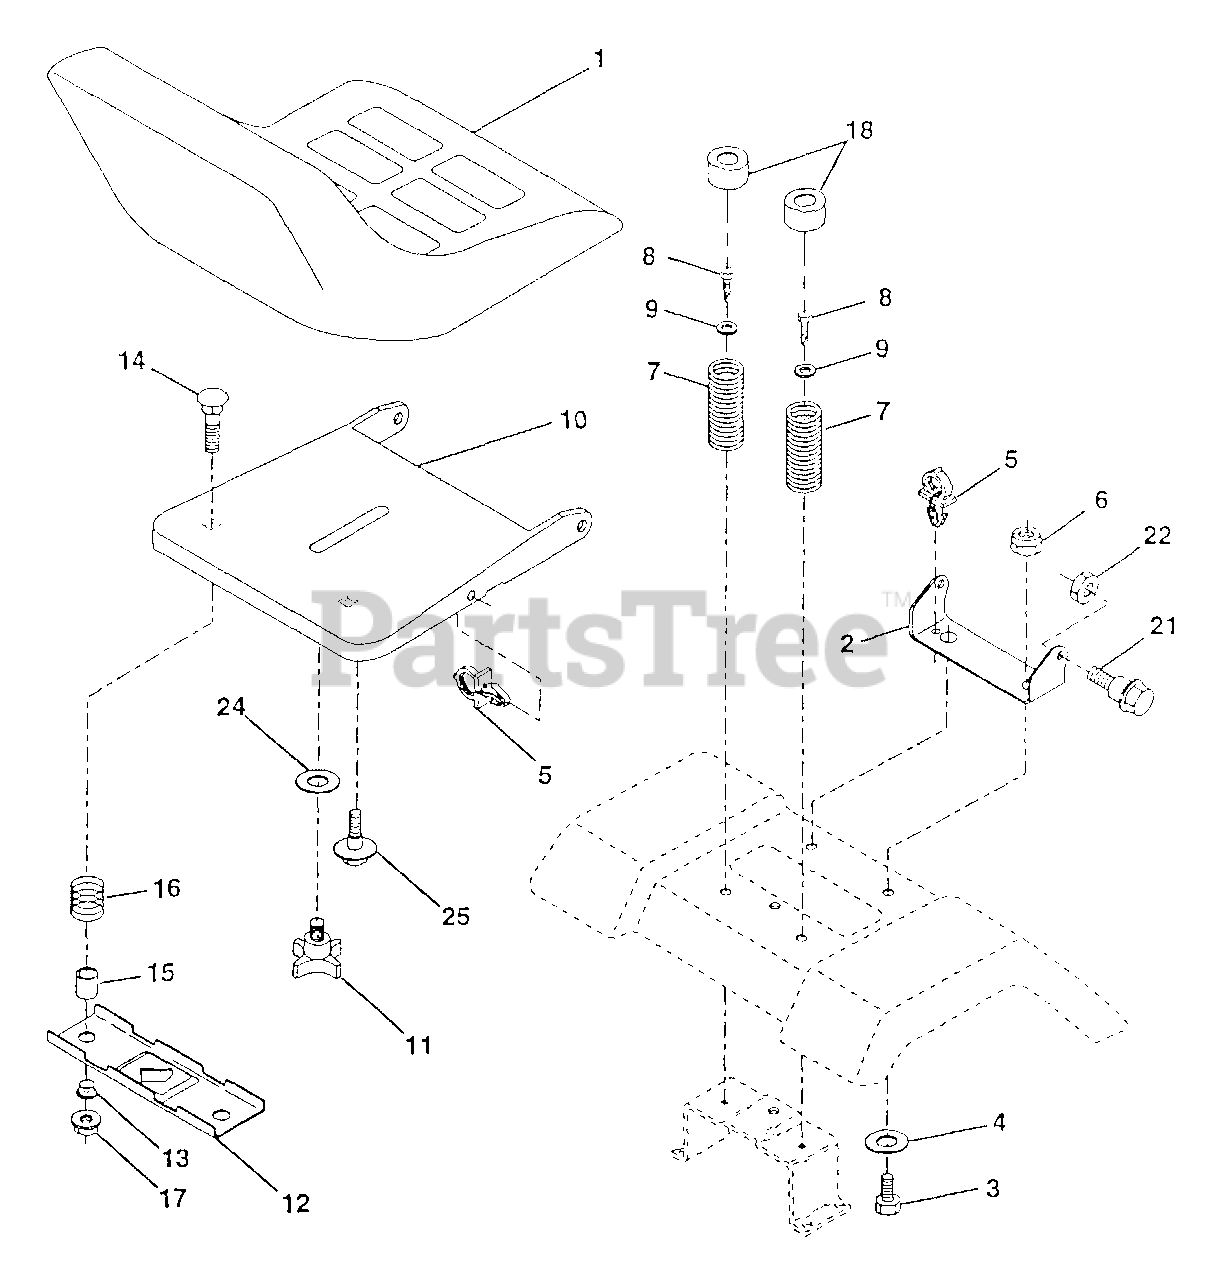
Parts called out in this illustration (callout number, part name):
2	Bracket Pivot Seat 8 720
3	Bolt Fin Hex 3/8-16 unc X 1
4	Washer 13/32 X 1 X 10 Ga
5	Clip Push-In
6	Nut Hex w/Ins. 3/8-16 Unc
7	Spring Seat Cprsn 2 250 Blk Zi (AYP part number)
8	Screw Thdrol 3/8-16 X 1 Ty-tt
9	Washer 13/32 X 1 X 14 Ga. (AYP part number)
10	Pan Seat (AYP part number)
11	Knob Seat 1/2-13 Unc Blk
12	Bracket Mounting Switch
13	Bushing Snap Blk Nyl 50 Id
14	Bolt Rdhd Sqnk 1/4-20 x 1-3/8 (AYP part number)
15	Spacer Split 28 x 88
16	Spring Cprsn
17	Nut Lock 1/4 Lge Flg Gr 5 Zinc (AYP part number)
18	Cap Spring Seat Blk
21	Bolt Shoulder 5/16-18 Unc (AYP part number)
22	Nut Hex Lock W/Ins 5/16-18
24	Washer 17/32 X 1-3/16 X 12 Ga.
25	Bolt Shoulder 5/16-18 X 62
